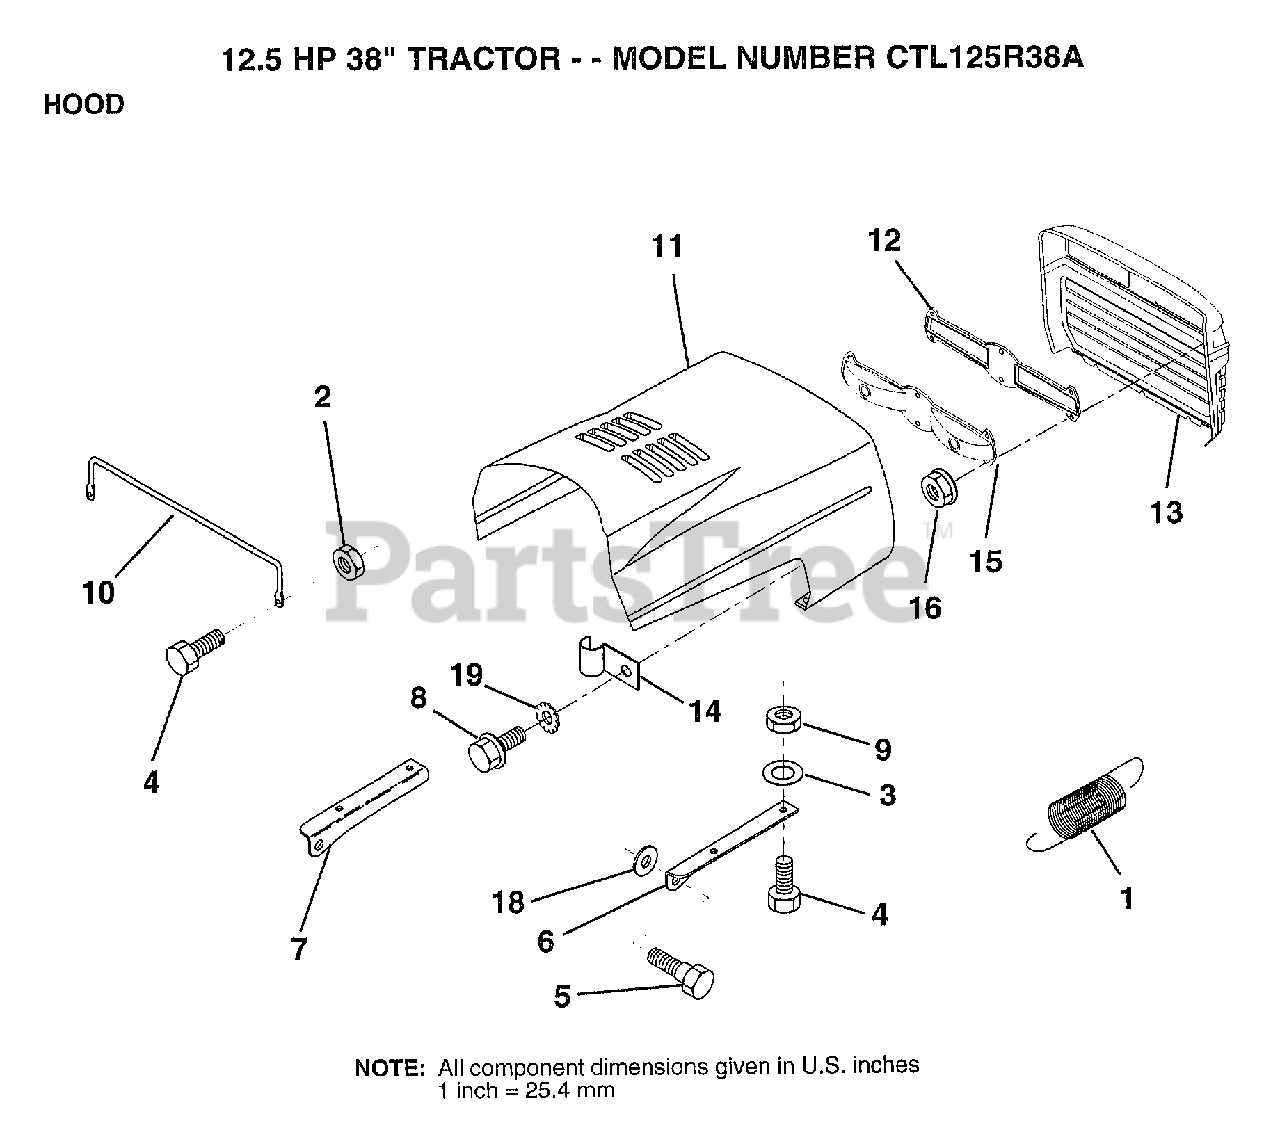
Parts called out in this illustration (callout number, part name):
1	EXT SPRING
2	NUT
3	WASHER
6	BRKT HOOD RH
7	BRKT HOOD LH
9	NUT
10	"BRACE,HOOD"
11	HOOD
14	CLIP T
16	NUT
18	WASHER
19	LOCKWASHER GT
